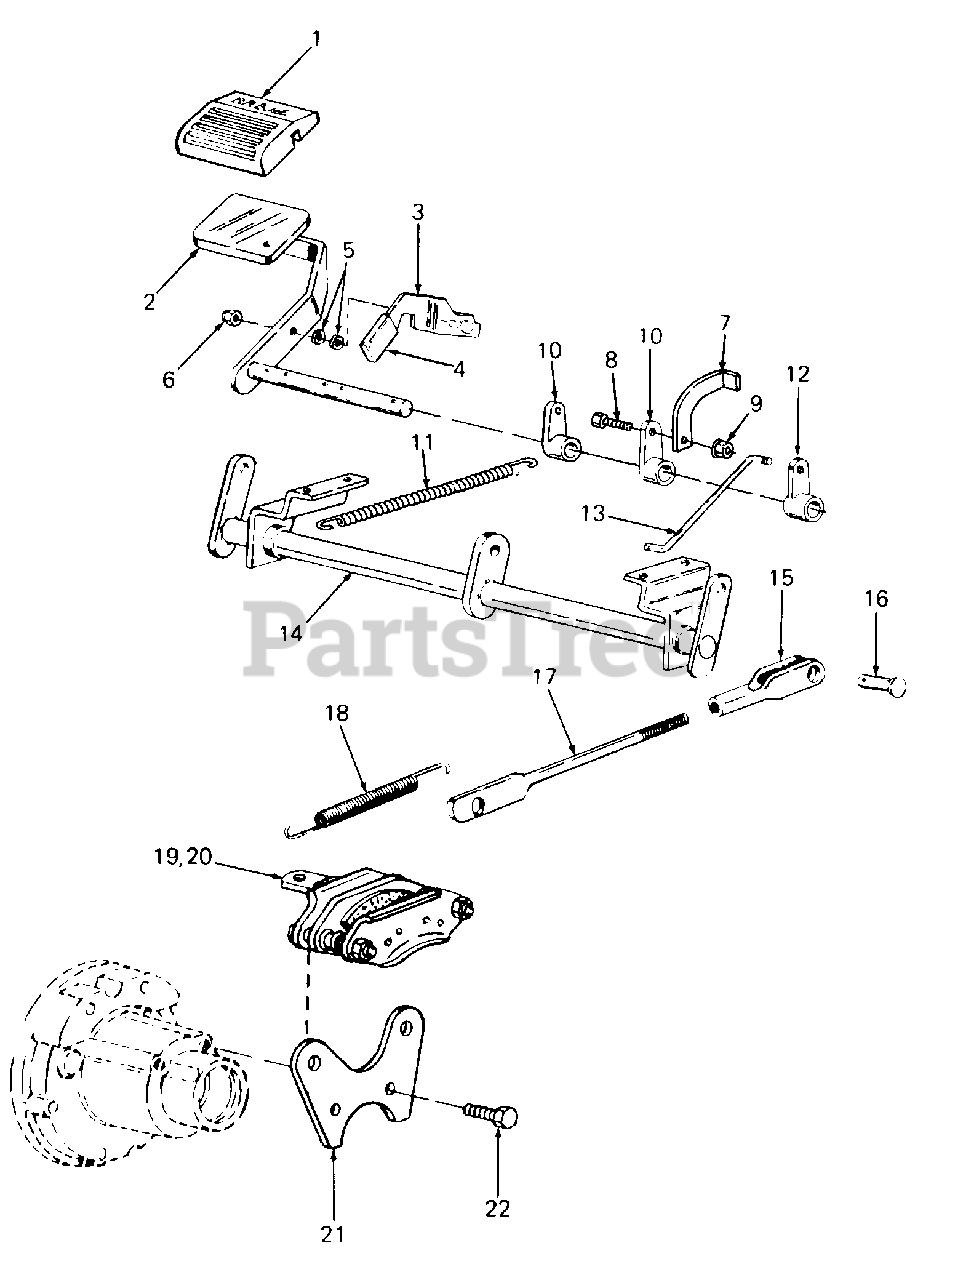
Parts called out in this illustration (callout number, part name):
1	Pad, Brake Pedal
2	Pedal Assy, Brake
5	Washer, Wave, 1/4 Dia
6	Nut, Hex Insert Lock, 1/4-20
8	Screw, Hex Cap, 3/8-16 X.75 Lg GR5
9	Nut, Hex Flanged Lock, 3/8-16 GR5
11	Spring, Return
15	Clevis, Adjustment
16	Pin, Clevis, 3/8 Dia X 1.0 Lg
17	Rod, Brake
18	Spring, Tension
19	Brake Kit, RH Caliper
21	Bracket, Brake Mounting
22	Screw, Hex Cap, 5/16-18 X 1.0 Lg GR5
